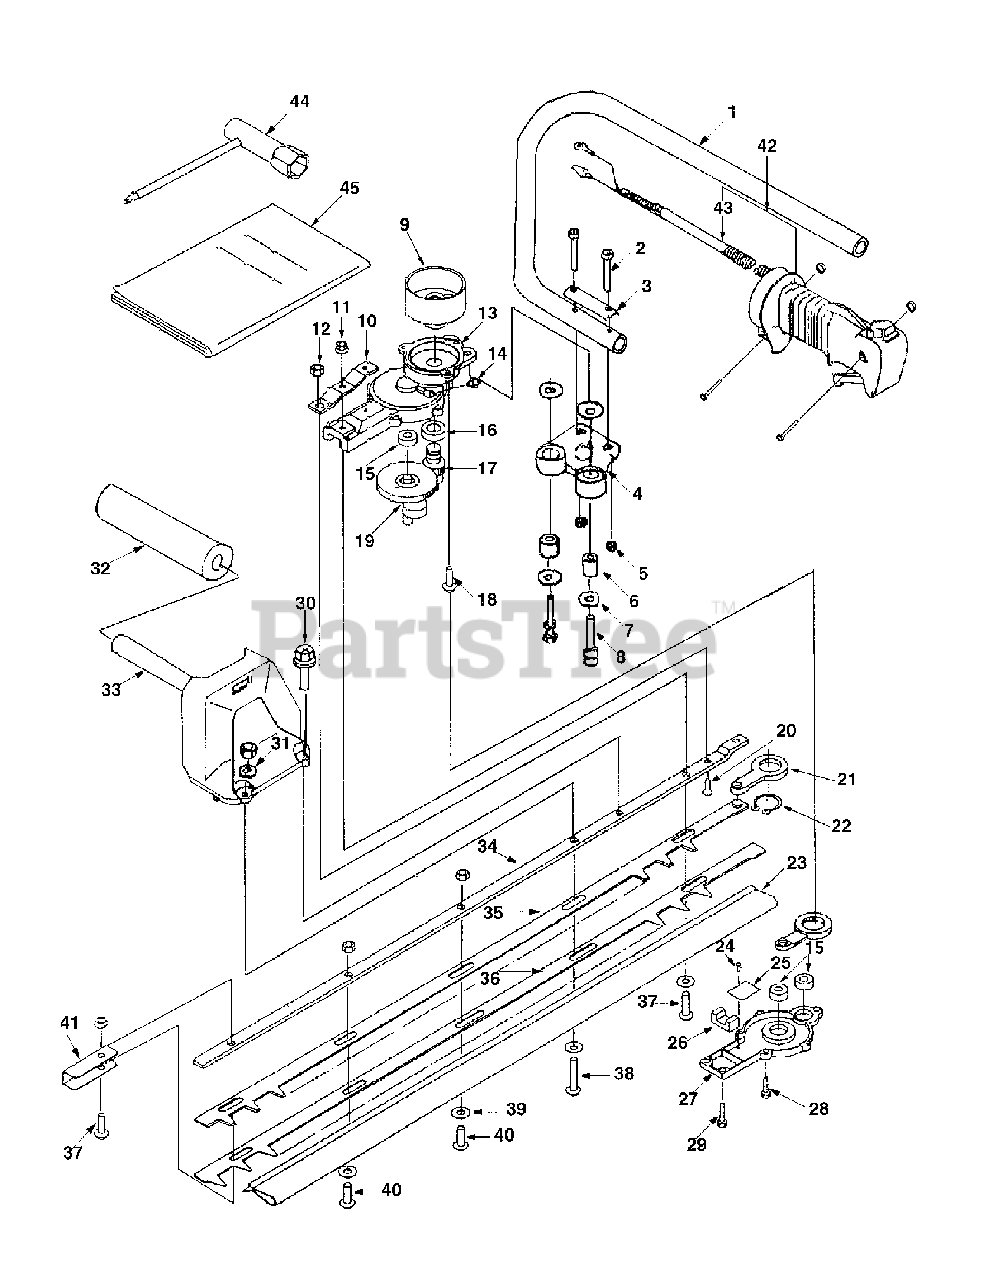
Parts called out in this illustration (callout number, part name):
2	Bolt; M5 x 30
3	Holder, Handle
4	Holder, Handle
8	Bolt; M6 x 26
9	Drum, Clutch
13	Case, Gear
14	Grease, Nipples
15	Ball Bearing; 608Z
16	Ball Bearing; 6001
17	Gear, Pinion
18	Screw; M6 x 14
19	Gear, Crank
20	Screw; M5 x 20
22	Snap Ring
23	Cover, Blade
24	Screw; M3 x 5
27	Case, Gear
28	Bolt; M5 x 16
29	Bolt; M5 x 20
30	Bolt; M6 x 18
42	Lever Ass'y., Throttle
43	Wire, Throttle
44	Spanner, Box
45	Instruction Book
